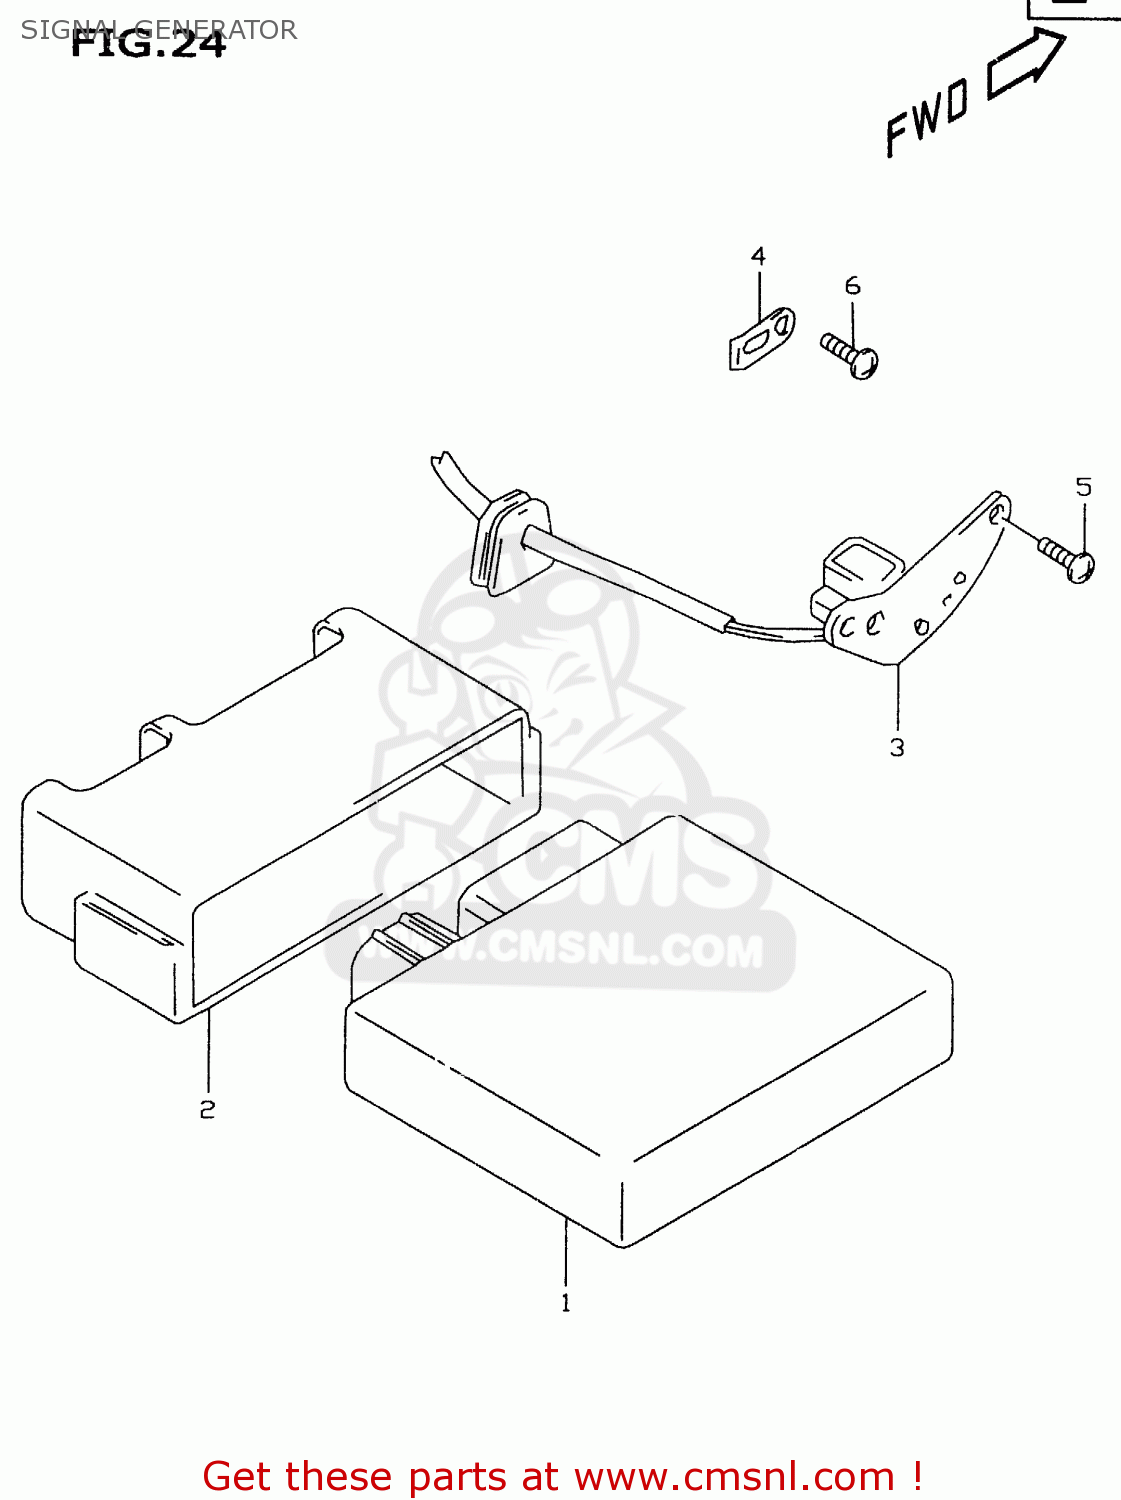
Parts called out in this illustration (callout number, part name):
1	CDI UNIT
2	CUSHION,IGNITER
3	STARTER,SIGNAL GENERATOR
4	CLAMP,SIGNAL GENERATORERATOR
5	SCREW
6	SCREW
